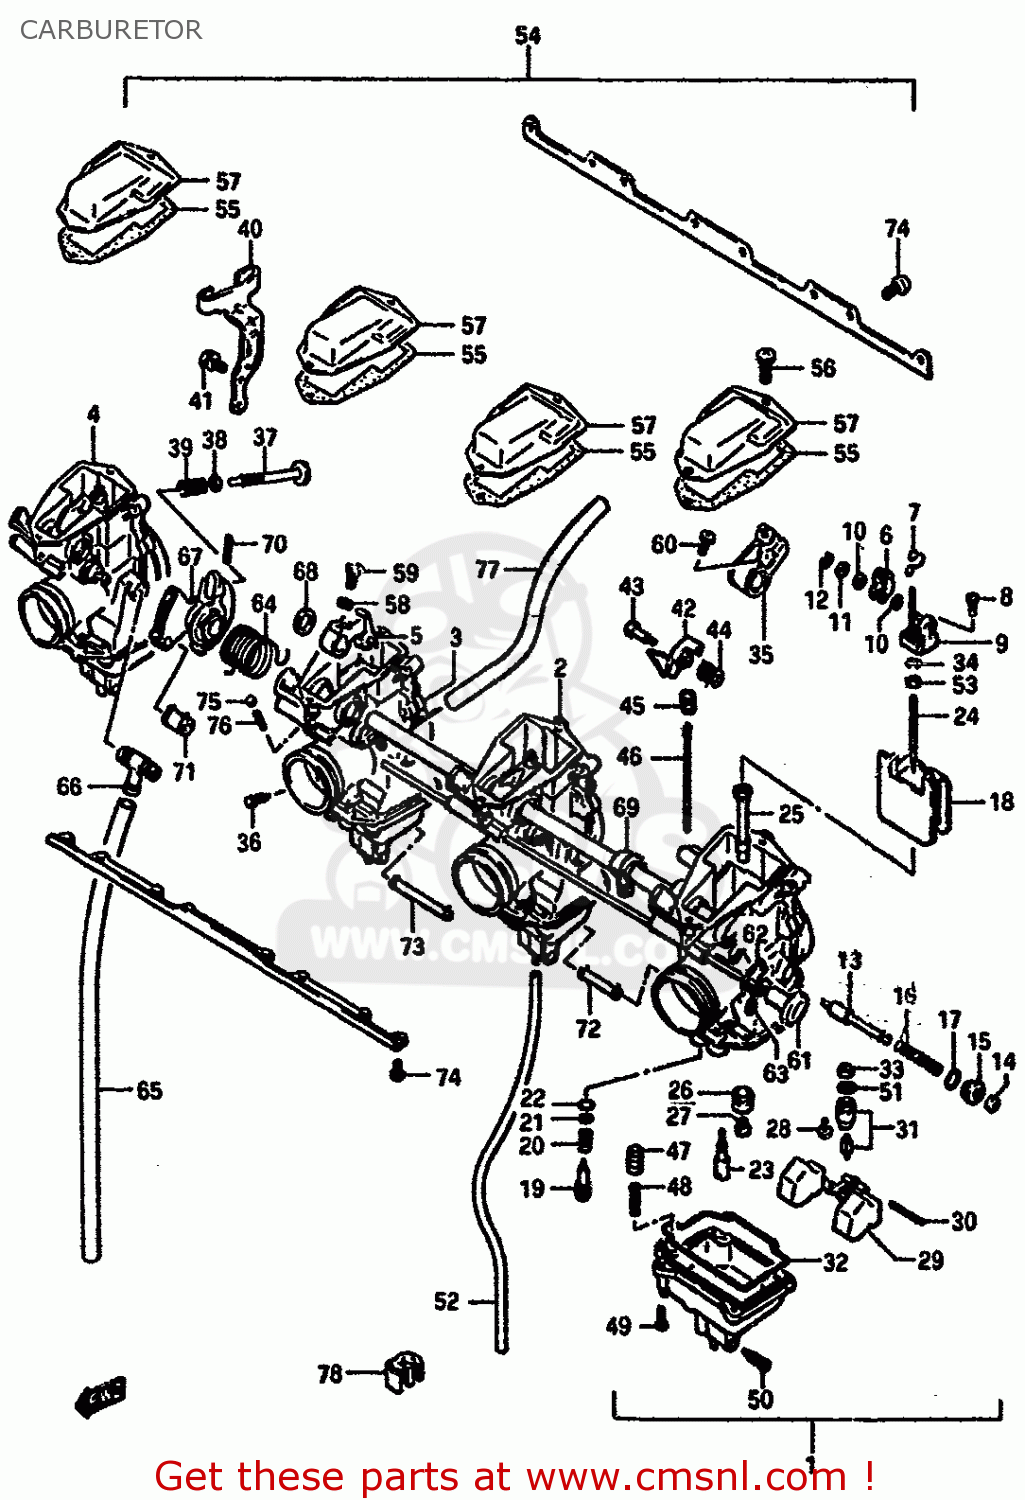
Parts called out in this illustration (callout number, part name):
1	CARBURETOR ASSY,LH
2	CARBURETOR ASSY,ML
3	CARBURETOR ASSY,MR
4	CARBURETOR ASSY,RH
5	ARM,THROTTLE
6	PLATE
7	SPRING
8	SCREW
9	CONNECTOR
10	GASKET (NAS)
11	WASHER
12	E-RING
13	PLUNGER
14	CAP,STARTER VALVE
15	GUIDE SCREW,PLUNGER
16	SPRING
17	O RING
18	VALVE, PISTON
19	SCREW,PILOT
20	SPRING
21	GASKET
22	O RING,PILOT AIR SCREW
23	JET,PILOT (32.5)
24	NEEDLE,JET
25	JET,NEEDLE(P-5)
26	RING,MAIN JET FIXING
27	JET,MAIN(97.5)
28	SCREW
29	FLOAT
30	PIN,FLOAT
31	VALVE ASSY,NEEDLE
32	O RING,FLOAT CHAMBER
33	FILTER
34	CLIP
35	LEVER ASSY
36	SCREW
37	SCREW,THROTTLE STOP
38	WASHER
39	SPRING
40	BRACKET
41	SCREW
42	LEVER
43	BOLT
44	SPRING,PLUNGER
45	BOOT, ACCELE PUMP ROD
46	ROD
47	PLUNGER
48	SPRING
49	SCREW
50	SCREW,DRAIN
51	O RING
52	HOSE SET (3X5X525)
53	WASHER,JET NEEDLE
54	FLANG SET
55	GASKET,CARBURETOR TOP (NAS)
56	SCREW
57	COVER,CARBURETOR,TOP
58	WASHER
59	BOLT
60	SCREW
61	SHAFT ASSY
62	LEVER
63	SCREW,THROTTLE ADJUST
64	SPRING
65	HOSE
66	NIPPLE
67	LEVER ASSY
68	RING,THROTTLE SHAFT
69	LEVER ASSY
70	PIN,THROTTLE SHAFT
71	HOSE SET (3X5X18)
72	HOSE SET (3X5X60)
73	HOSE SET (3X5X72)
74	SCREW
75	BALL,CARBURETOR
76	SPRING
77	HOSE
78	CLIP
